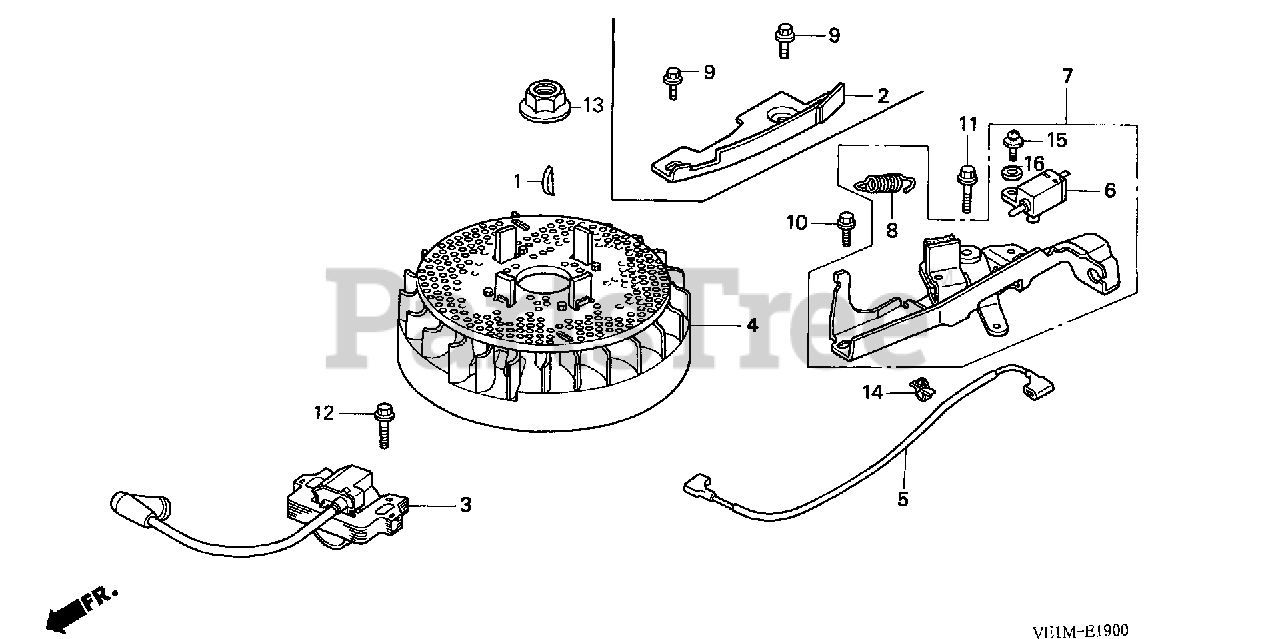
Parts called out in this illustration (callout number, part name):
1	KEY, SPECIAL WOODRUFF (25X18)
2	PLATE, SIDE
3	COIL ASSY., IGNITION (USE FOR F/W OF TEC) (TEC)
4	FLYWHEEL ASSY. (TEC) (USE FOR IGN. COIL OF TEC)
5	WIRE, STOP SWITCH
9	BOLT, FLANGE (6X12) (CT200)
12	BOLT, FLANGE (6X20) (CT200)
13	NUT, SPECIAL (14MM)
14	CLIP A, CABLE (3.8MM BLACK) (NIFCO)
